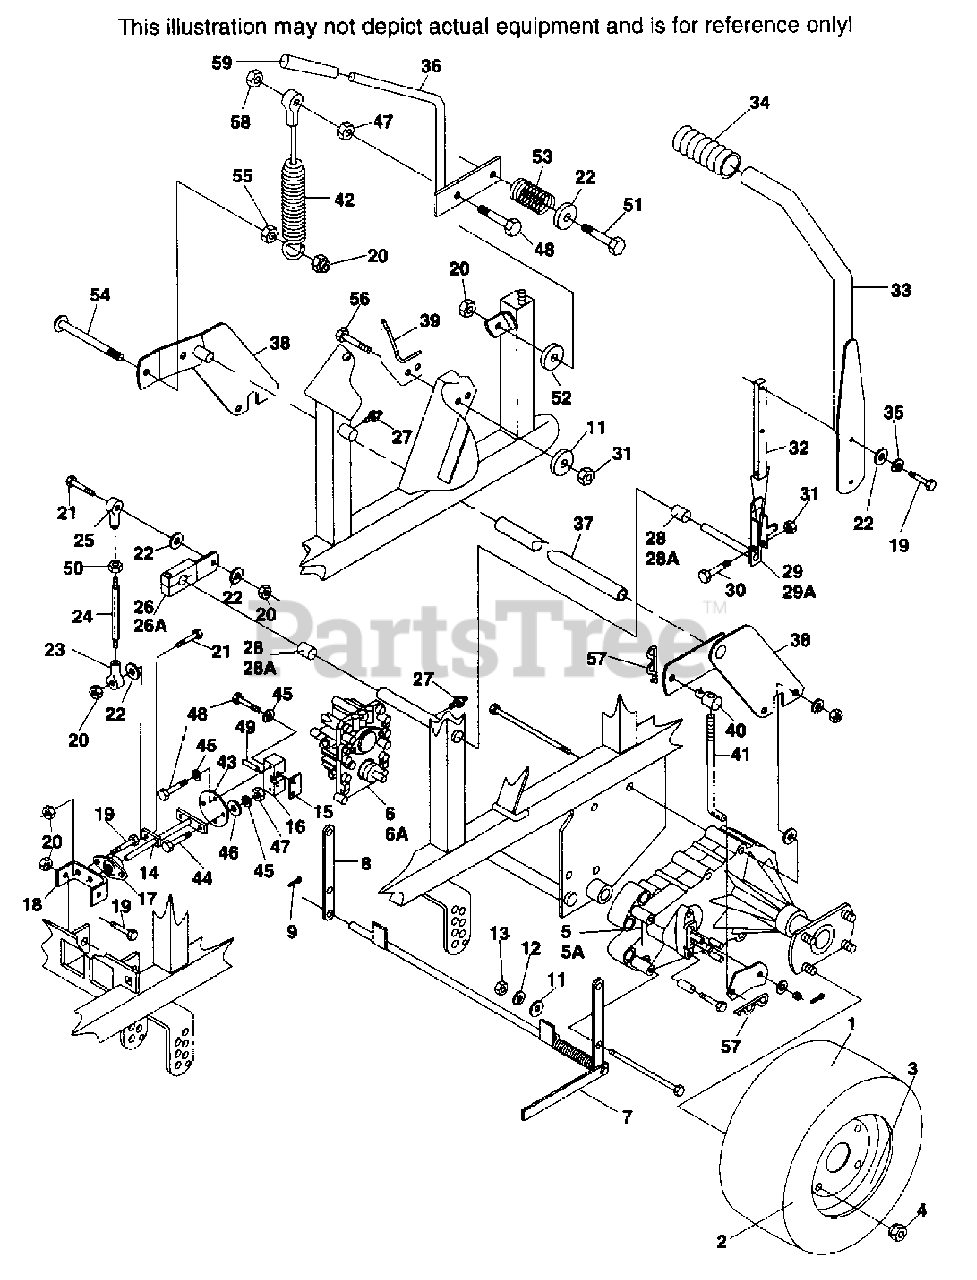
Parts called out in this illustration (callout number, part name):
1	DRIVE WHEEL ASSEMBLY, COMPLETE
2	TIRE ONLY
3	RIM ONLY
4	LUG NUT, 1/2-20
5	AXLE, LH
5A	AXLE, RH
6	PUMP, LH
6A	PUMP, RH
7	DUMP VALVE, LEVER WELDMENT
8	MOUNTING BRACKET
9	HAIR PIN
14	PUMP WELDMENT SHAFT
15	CLAMP PLATE
16	BLOCK, PUMP CONTROL
17	BEARING
18	BEARING BRACKET
22	FLATWASHER, 3/8"
23	BALL JOINT, LH THREAD
24	LINK, TURNBUCKLE
25	BALL JOINT, RH THREAD
26	LEVER, PUMP TRANSFER LH
26A	LEVER, PUMP TRANSFER RH
27	GREASE FITTING
28	BUSHING, LH
28A	BUSHING, RH
29	CONTROL LEVER, LH
29A	CONTROL LEVER, RH
32	BAR CONTROL LEVER
33	CONTROL HANDLE
34	GRIP, CONTROL HANDLE
36	LEVER WELDMENT, PARKING BRAKE
37	CAM WELDMENT, PARKING BRAKE
38	PLATE, PARKING BRAKE
39	LATCH, BRAKE
40	SWIVEL JOINT
41	ROD, BRAKE
42	CABLE ASSEMBLY, PARKING BRAKE
43	PLATE, COUPLER
49	ROLL PIN, 3/16 X 3/4"
52	FLATWASHER, 3/8 X 1-1/2" X 16 GA.
53	SPRING, BRAKE LEVER
57	HAIR PIN, 1/16" DIAMETER
59	GRIP, PARKING BRAKE
